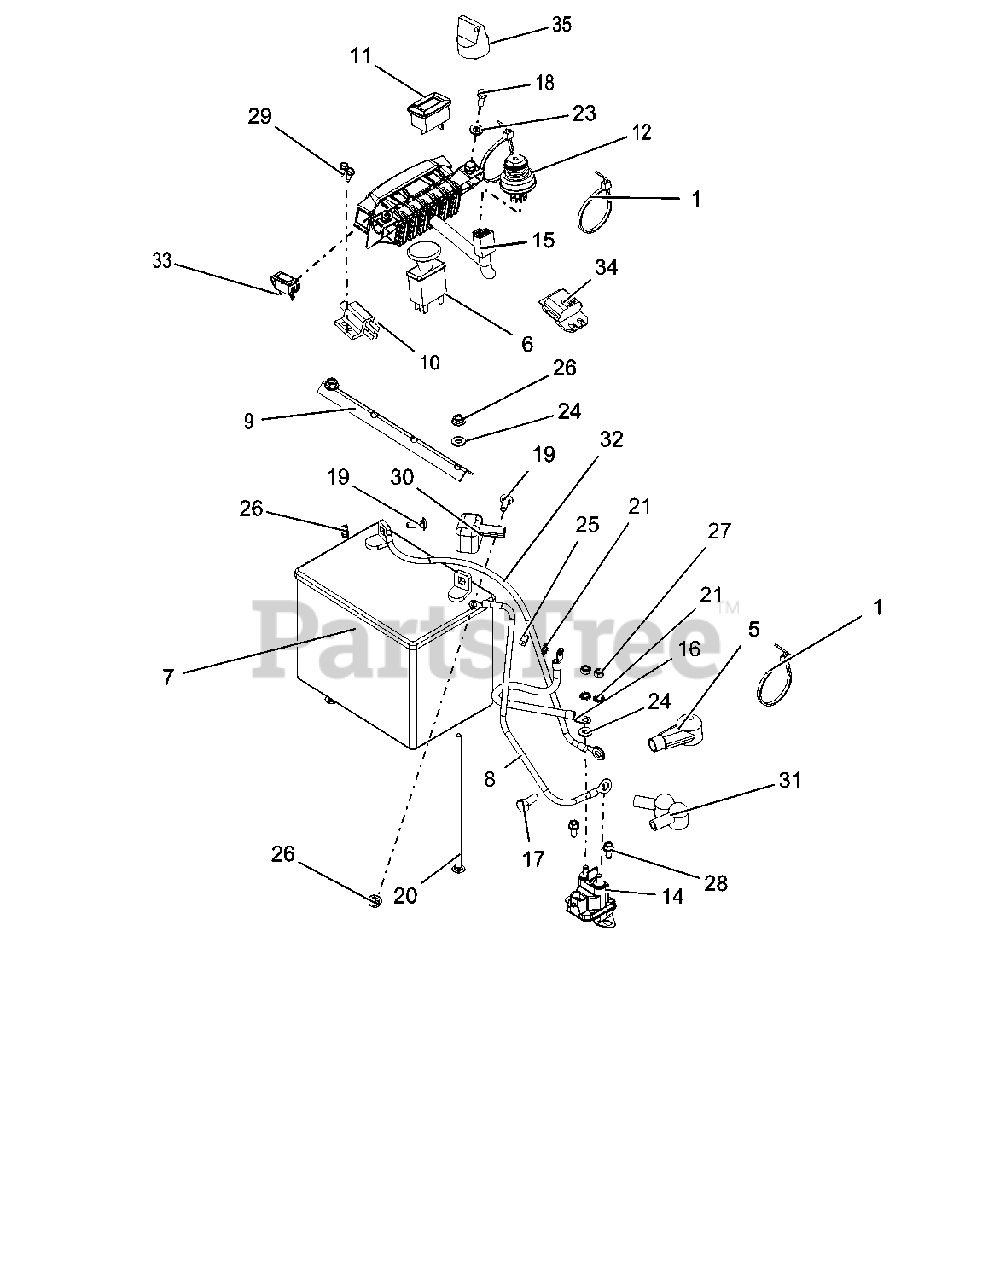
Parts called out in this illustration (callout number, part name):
1	CABLE TIE, .15 X 8.50
5	BOOT, BATTERY TERMINAL-RED
6	SWITCH, CLUTCH
7	BATTERY, 300 CCA 10U1L
8	CABLE, STARTER 13.00"
9	HOLD DOWN
10	SWITCH- DOUBLE POLE N.O./N.O.
11	METER, HOUR W/MAINTENANCE
12	SWITCH, IGNITION
14	SOLENOID, STARTER (SEALED)
15	HARNESS, PROSTANCE WIRING
15	FUSE,10 AMP MINI-ATC
15	FUSE,15 AMP MINI-ATC
15	FUSE,20 AMP MINI ATC
15	RELAY,MICRO5 TERML W/RESISTOR
15	DIODE, CONNECTOR SHELL
15	FUSE, 20 AMP BLADE S/O
16	CABLE, POS W/(2)1/4 RING 9.0LG
17	@BLT-HEX M8-1.25X20 YWZC
18	@BLT-HEX M6-1X16 YWZC
19	@BLT-RDHDSQNK .25-20X.75 G5YZ
20	BLT-RDHDSQNK .25-20X7.50 GR2YZ
21	@WSHR-LK-EXT.262X.502X.026YWZC
23	@WSHR-LK .31X.078 REG YWZC
24	@WSHR-FL-STL.281X.62X.065 YWZC
25	@NUT-LK-CTR .25-20 YWZC
26	@NUT-SPNLK-FLG .25-20 YWZC
27	NUT-HEX M6X1.0 YWZC
28	SCR-TAP .25-20X.50 HWH TR YWZ
29	@SCR-TAP 10-24X.50 HWH TR YWZC
30	INSULATOR
31	BOOT, EYELET TERMINAL
32	CBL,NEGATIVE BATTERY 20.00
33	LIGHT,INDICATOR
34	MODULE,INTERLOCK,DELAY, 1801
35	KEY, W/ SHIELD
